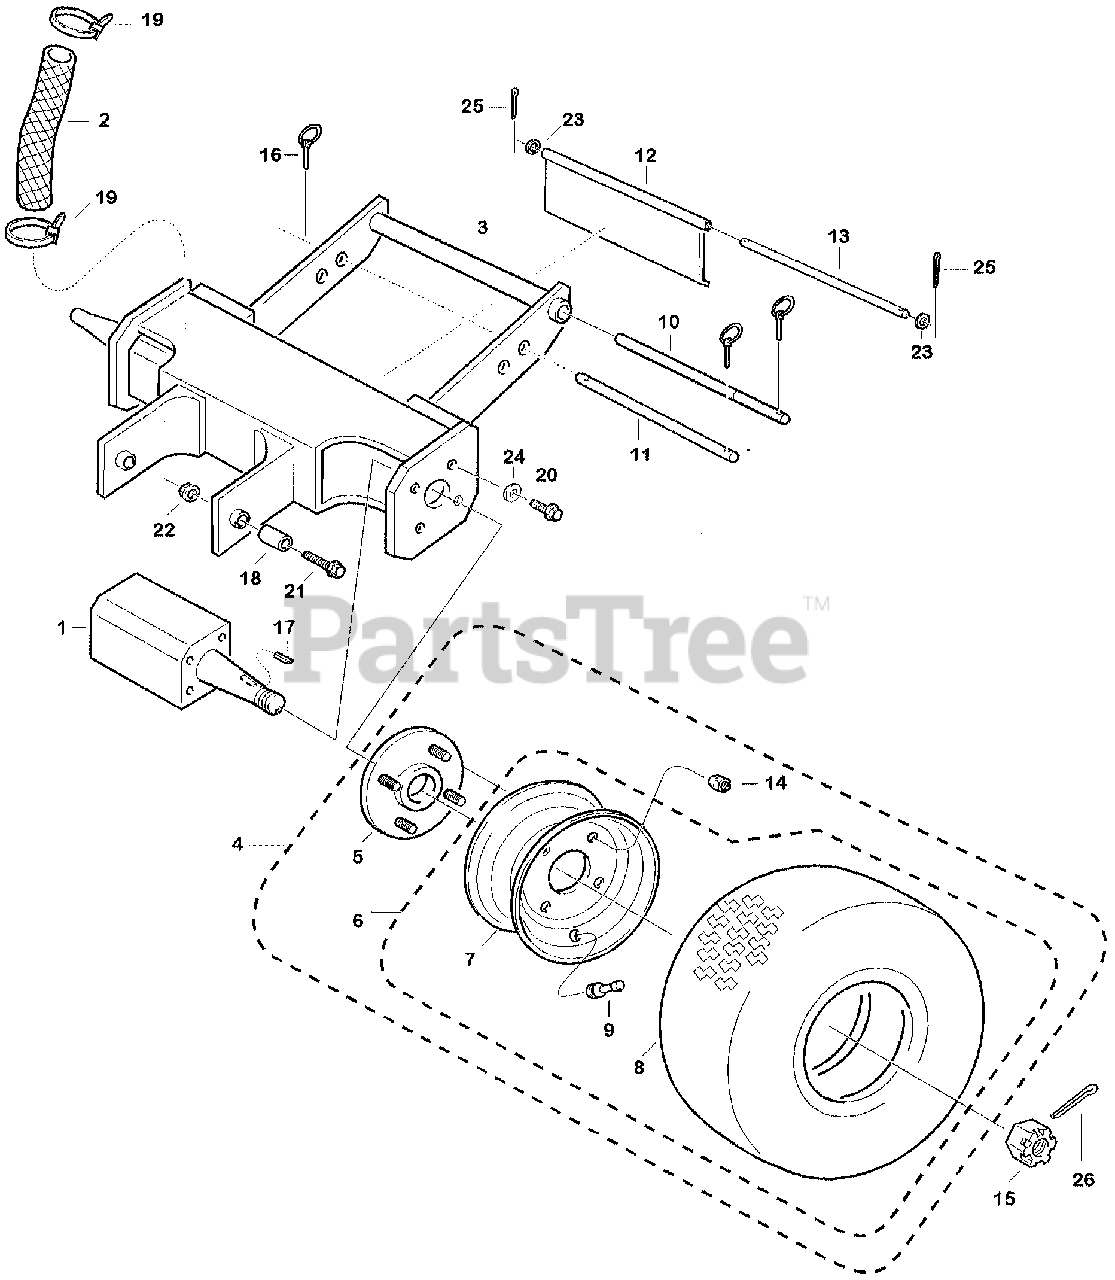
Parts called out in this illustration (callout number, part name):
1	MOTOR ASSY., HYDRAULIC
2	COVER, HOSE
4	WHEEL ASSY., TRACTION
5	HUB, WHEEL
6	WHEEL ASSY., RR.
7	WHEEL, RR.
8	TIRE, RR.
9	VALVE, RIM
10	BAR, HEIGHT
11	SHAFT, HEIGHT
12	SHIELD, RR.
13	ROD, RR. SHIELD
14	LUG NUT, HEX. (1/2"-20)
15	NUT, STRAIGHT SLOT (3/4"-16)
16	QUICK CLIP
17	KEY, WOODRUFF
18	BUSHING, AXLE
